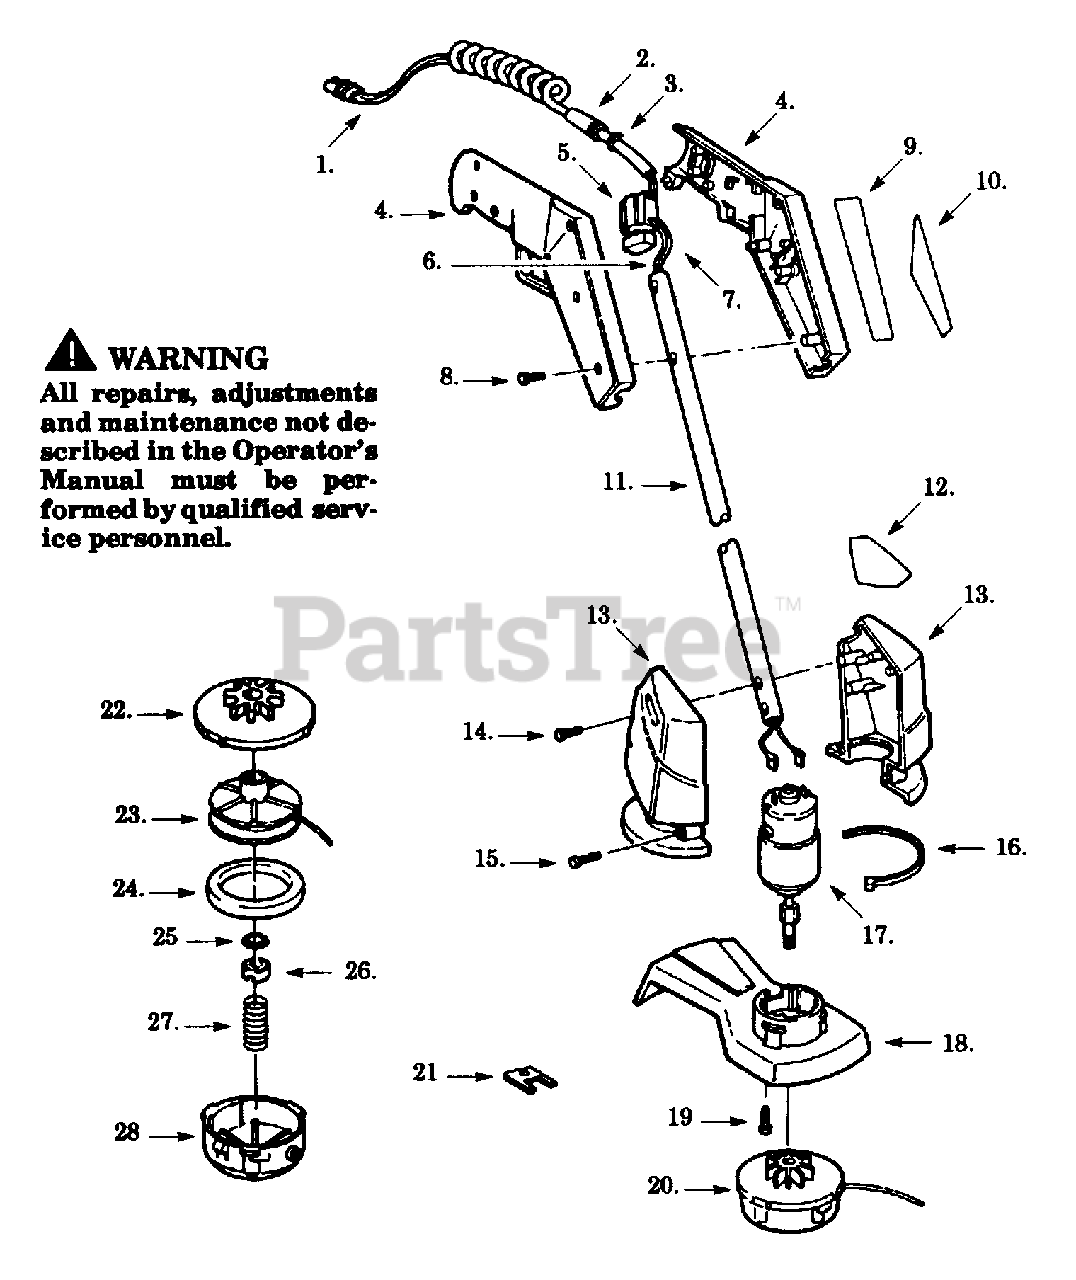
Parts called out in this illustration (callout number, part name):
1	Coiled Cord
2	Rubber Strain Relief
3	Strain Relief
4	Handle Set
5	Trigger Switch
6	Lead Wire (Black)
7	Lead Wire (Red)
9	Handle Label
10	Warning Label
12	Top Hsg. Label
13	Housing Set
16	Tie Wrap
17	Motor/Adapter Ass'y.
18	Guard/Blade Ass'y.
20	Head Ass'y.
21	Spanner Wrench
22	Rear Plate
23	Spool & Line
24	Foam Pad
26	Adapter Nut
28	Hub Ass'y.
